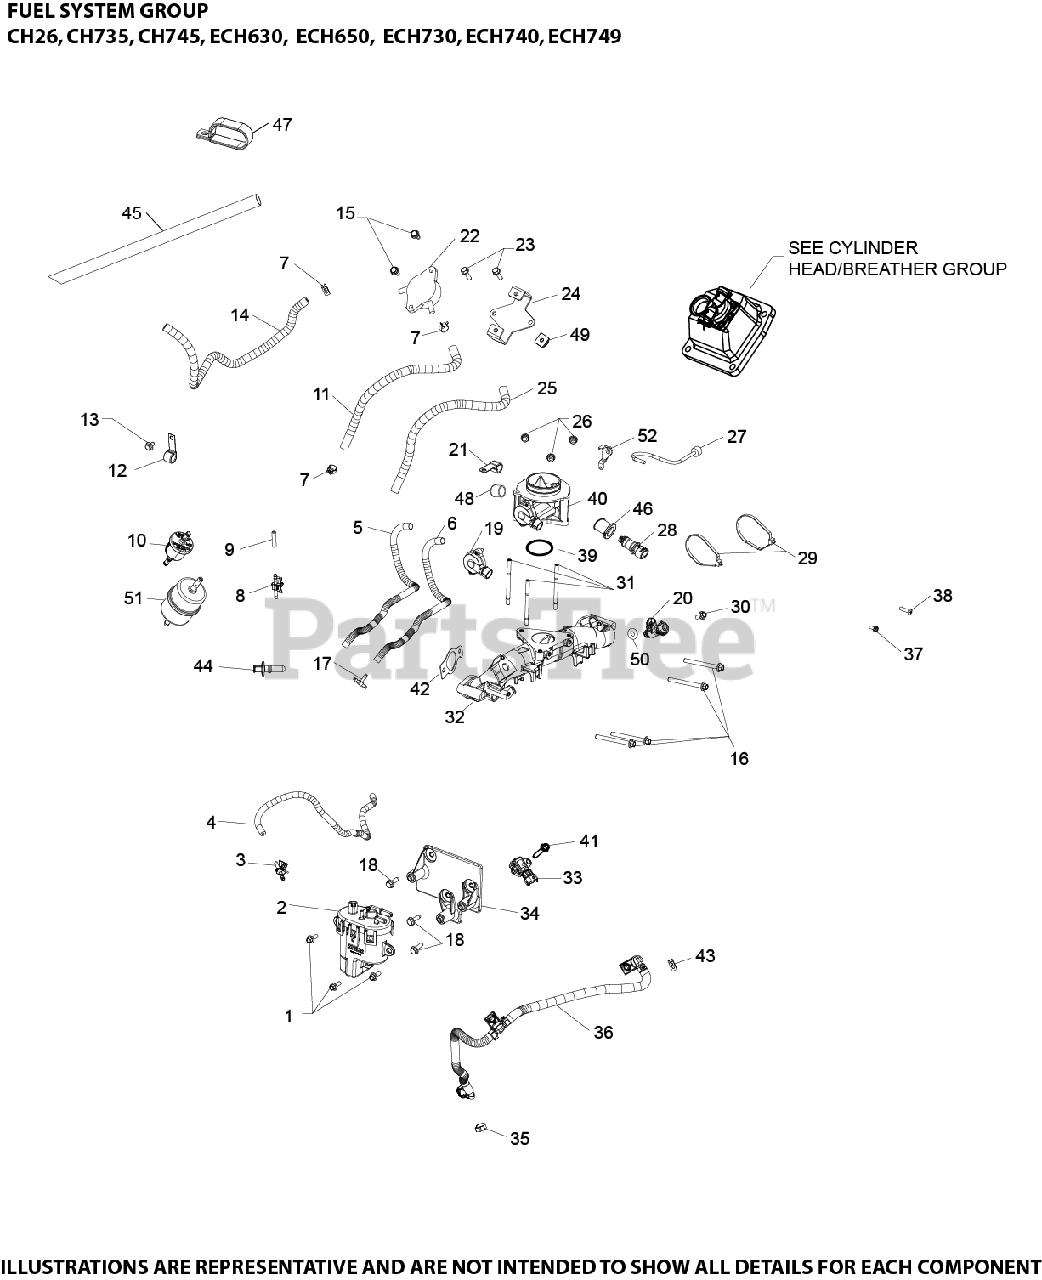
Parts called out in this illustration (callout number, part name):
1	SCREW, FLG M6X1.0X16
2	PUMP, FUEL MODULE - USE 25 393 14-S
4	HOSE, EVAPORATIVE (15.0)
5	SLEEVE, ANTI-ABRASION
7	CLAMP, HOSE (KM)-USE 25 237 31-S
8	CONNECTOR, EVAPORATIVE
9	CAP, MASKING
10	FILTER, FUEL
11	HOSE,LW PERM.FUEL 24.00"-USE 25 111 81-S
16	SCREW, FLG M6X1.0X60
17	TEE CONNECTOR
18	SCREW, THREAD FORMING
19	SENSOR, THROTTLE POSITION
20	INJECTOR, FUEL
21	CLIP, CABLE
25	SLEEVE, FUEL LINE
26	NUT, FLG M6X1.0
28	SENSOR, AIR TEMPERATURE
30	SCREW, FLG M6X1.0X16
31	STUD,M6X1.0X84
32	KIT, MANIFOLD
33	SENSOR, MAP
34	BAFFLE, FUEL MODULE
35	CLAMP, HOSE
36	FUEL HOSE ASSY (90* FITTING)
40	BODY, THROTTLE ASSEMBLY INCLUDES THROTTLE POSITION SENSOR
41	SCREW, FLG M6X1.0X25
42	GASKET, INTAKE MANIFOLD USE 24 041 79-S
43	CLAMP, OETIKER
50	KIT, FUEL INJECTOR O-RING
